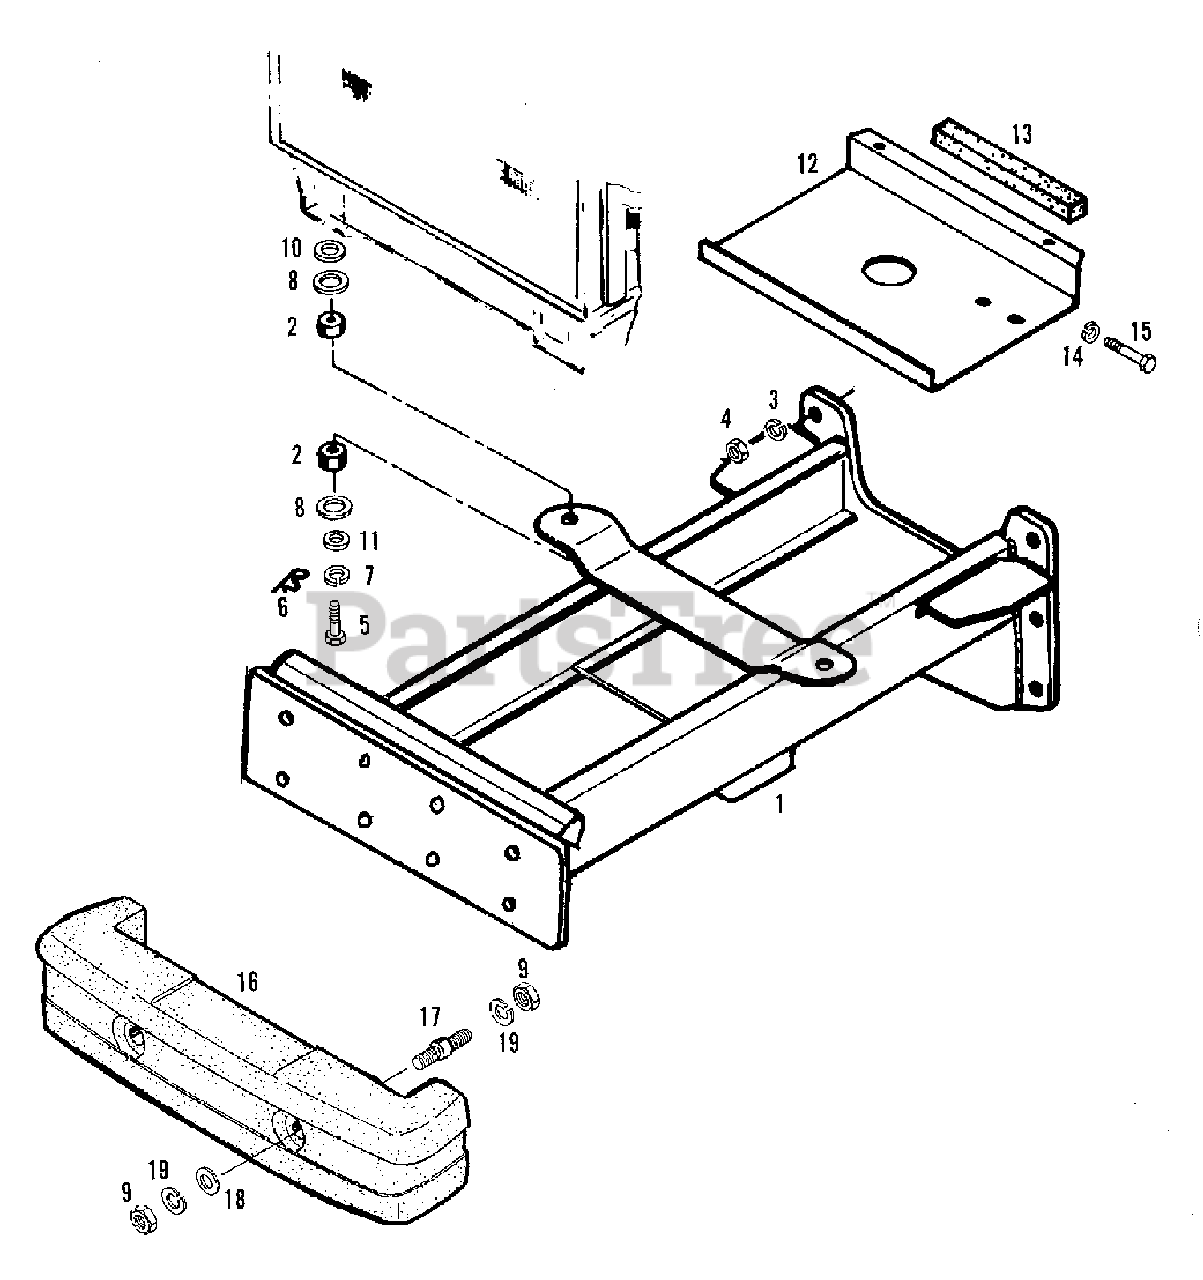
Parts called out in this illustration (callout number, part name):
3	LOCKWASHER, M14
7	LOCKWASHER, M10
14	LOCKWASHER, M12
16	FRONT WEIGHT (Order from MACHINERY)
18	WASHER, M14
19	LOCKWAHER, M14
